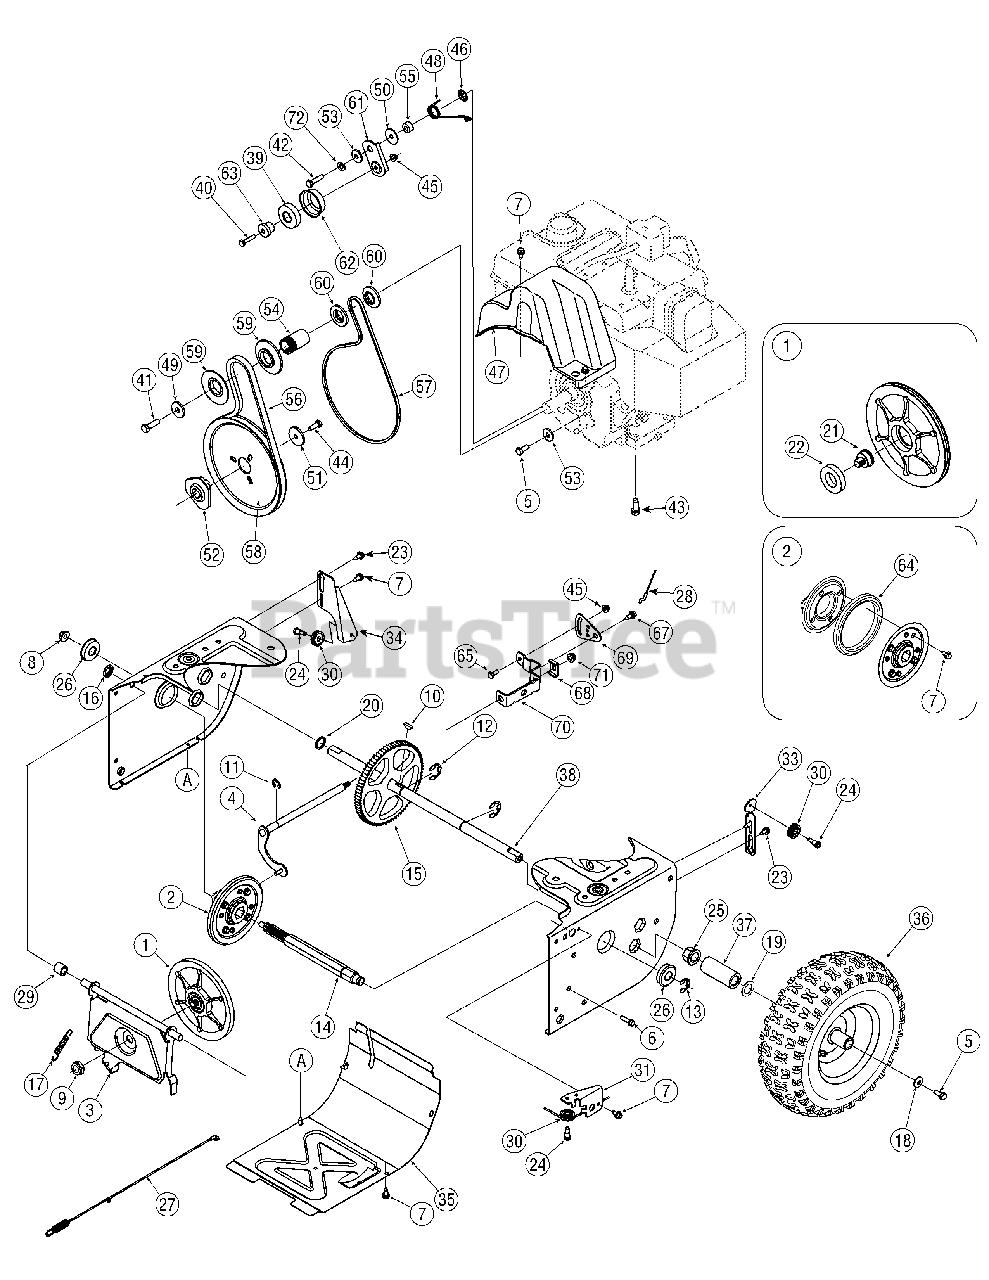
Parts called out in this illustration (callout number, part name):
1	Disc, Friction Wheel
2	Friction Wheel Assembly, 5.5 OD
3	Support Bracket, Friction Wheel
4	Shift Assembly, Rod
5	Hex Screw, 5/16-24, .750, Gr5
6	Screw, 1/4-20, 1.000
7	Screw, 1/4-14 x .625
8	Nut, Flange Lock, 3/8-16, Nylon
9	Nut, Jam Lock, 5/8-18, Gr5, Nylon
10	Key, Hi Pro, 3/16 x 3/4 Dia.
11	E-ring, .500 Dia.
12	E-ring, Retaining, .875 Dia.
13	E-ring, .750 Dia.
14	Hex Shaft, .8125, 7-Tooth
15	Gear, 80-Tooth
16	Speed Nut, .500
17	Extension Spring
18	Washer, Bell, .340 x .872 x .060
19	Washer, Flat, .793 x 1.24 x .060
20	Washer, Flat, .75 x 1.00 x .060
21	Pin, Friction Disc
22	Ball Bearing, 30 x 55 x 13
23	Screw, Shoulder, .37 x .105, 1/4-20
24	Screw, 1/4-28, .375
25	Bearing, Hex Flange x .75 ID
26	Bearing, Ball, 17 x 40 x 12
27	Clutch Cable, Wheel, 44.95"
28	Speed Selector Cable
29	Spacer, .508 ID x .75 OD x .68
30	Roller, Cable
33	Guide Bracket, Auger Cable
34	Guide Bracket, Drive Cable
36	Rim 16 x 4.8
36	Tire 15 x 5
36	Valve
37	Spacer, 1.25 x .75 x 3.0
38	Axle, .75 x 22"
39	Ball Bearing
40	Hex Screw, 1/4-20, 1.25, Gr5
41	Hex Screw, 3/8-24, 1.25, Gr8
42	Hex Screw, 5/16-24, 1.25, Gr5
43	Screw, Sems, 3/8-16, 1.00
44	Hex Screw, 5/16-24, .875, Gr8
45	Nut, Flange Lock, 1/4-20, Nylon
46	Nut, Push-on, .25 Dia.
47	Cover, Belt
48	Spring, Torsion, .850 ID x .354
49	Washer, Flat, .406 x 1.25 x .157
50	Washer, Flat, .330 x 1.25 x .06
51	Washer, Flat, .34 x 1.50 x .150
52	Pulley, Adap, .75 Dia W/dd
53	Spacer, Shoulder
54	Spacer, .875 ID x 1.185 OD
55	Spacer, .340 x .750 x .360
56	Belt, Auger Drive
57	Belt, Wheel Drive
58	Pulley, Auger Drive, 8.1 x .5
59	Pulley, Half, V x 2.600 OD
60	Pulley, Half, 1/4-V x 1.5 OD
61	Idler Bracket, Wheel Drive
62	Sleeve, Bearing Idler
63	Spacer, Shoulder, .26 x .79 x .538
64	Rubber, Friction Wheel, 5.5 OD
65	Hex Screw, 1/4-20, .620, Gr5
66	Spring, Torsion, .750 ID x .968
67	Screw, Shoulder, .37 x .105, 1/4-20
68	Bracket, Shift Spacer
69	Pivot Bracket, Speed Selector
70	Shift Bracket, Speed Selector
71	Nut, Flange Lock, 5/16-18, Nylon
72	Washer, Lock, 5/16
